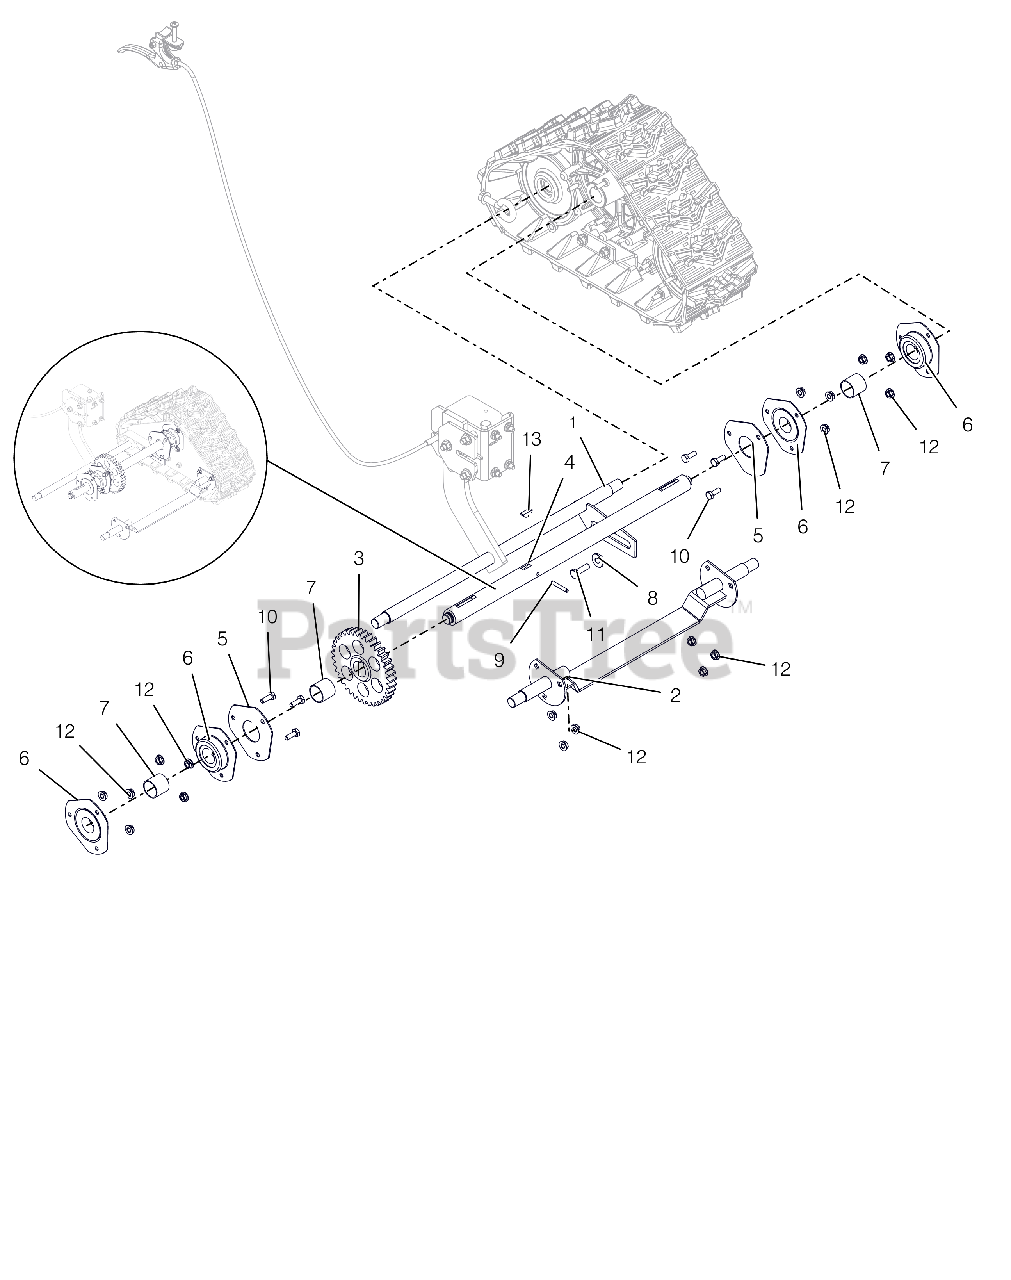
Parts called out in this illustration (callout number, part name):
1	AXLE, REAR - DELUXE TRACK
2	AXLE, FRONT-COMPACT TRACK
3	GEAR, SPUR
4	AXLE, TRACK-DELUXE
5	PLATE, BEARING SPACER
6	BRG-FLG 1.003/1.000 3 BOLT
7	BSHG-SLV, 1.012X1.125X1.00
8	BSHG-FLG .325X.499X.3X.875
9	PIN-ROLL .188X1.25
10	@BLT-HEX .25-20X.75 GR5 YWZC
11	@BLT-HEX .31-18X1.00 GR5 YWZC
12	@NUT-LK-CTR-FLG .25-20 YWZC
13	KEY-WDRF .25X.750X.313 SAE91
